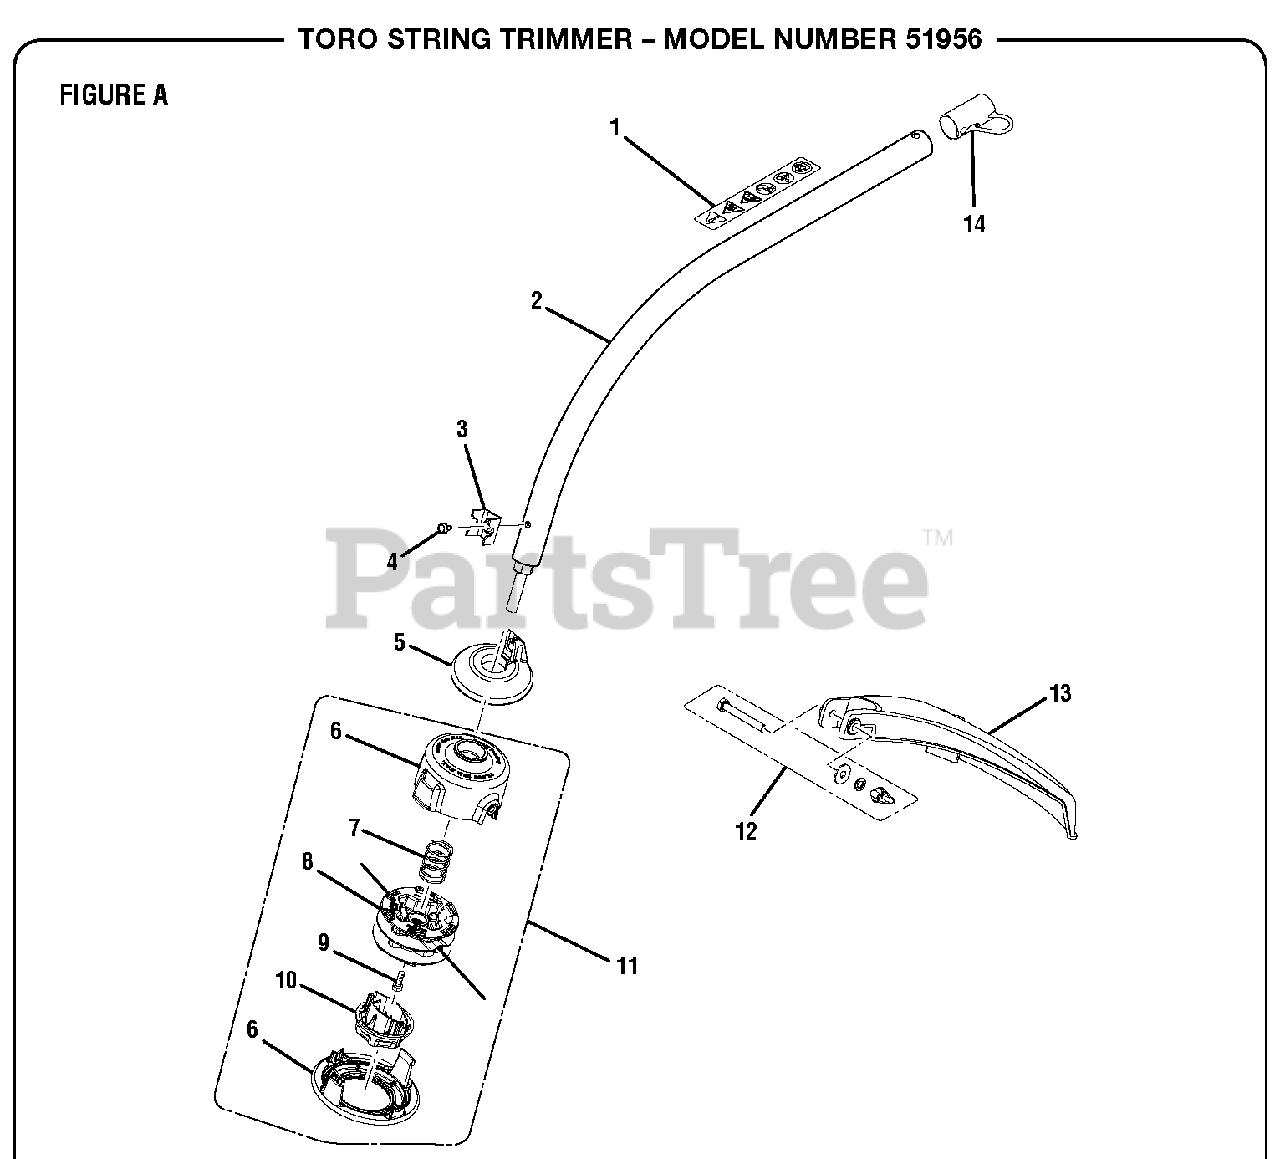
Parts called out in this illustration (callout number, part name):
1	Warning Label
2	Curved Shaft Assembly
4	Screw (#10-32 x 3/8 in, Hex Washer Hd)
5	Grass Shield
6	Stringhead Housing
7	Compression Spring
8	Spool
9	Bolt (5/16-18 x 1/2 in)
10	Bump Knob
11	Trimmer Head Assembly (095)
12	Fastener Parts Kit
13	Guard
14	Hanger Cap
